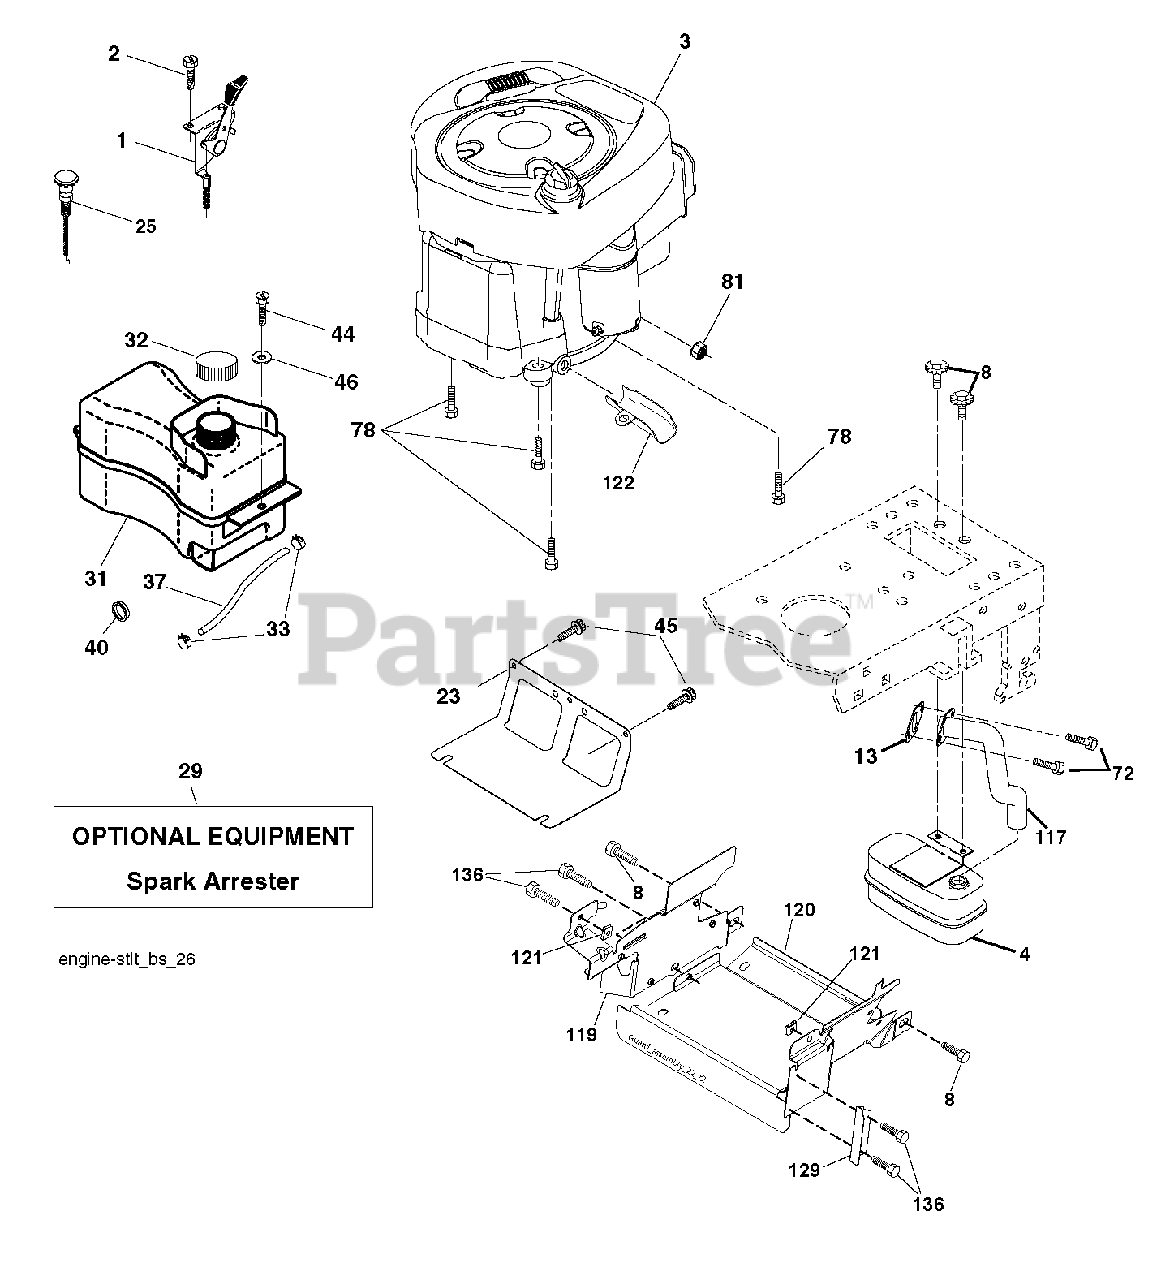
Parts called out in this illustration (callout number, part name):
1	CONTROL TH/CH FLAG
2	SCREW
4	MUFFLER.SINGLE.CYL.KOHL/B&S
8	BOLT, 5/16-18 X 1 3/4
13	REPL BY 532 27 22-93
23	SHEILD.BROWNING.DBR.GUARD
29	ARRESTER SPARK (OPTIONAL)
32	CAP ASM.FUEL.2.25"FR.
33	HOSE CLAMP
37	LINE.FUEL.20
40	GROMMET T
44	SCREW HEXWSHR 1/4-20X3/4
45	SCREW, 3/8-16X3/4
72	SCREW.SOCKET HD.5/16-1
78	SCREW.3/8-16
81	NUT
117	EXHAUST.TUBE.B&S.
122	EXTENSION DRAIN OIL
136	SCREW.1/4-20X5/8
